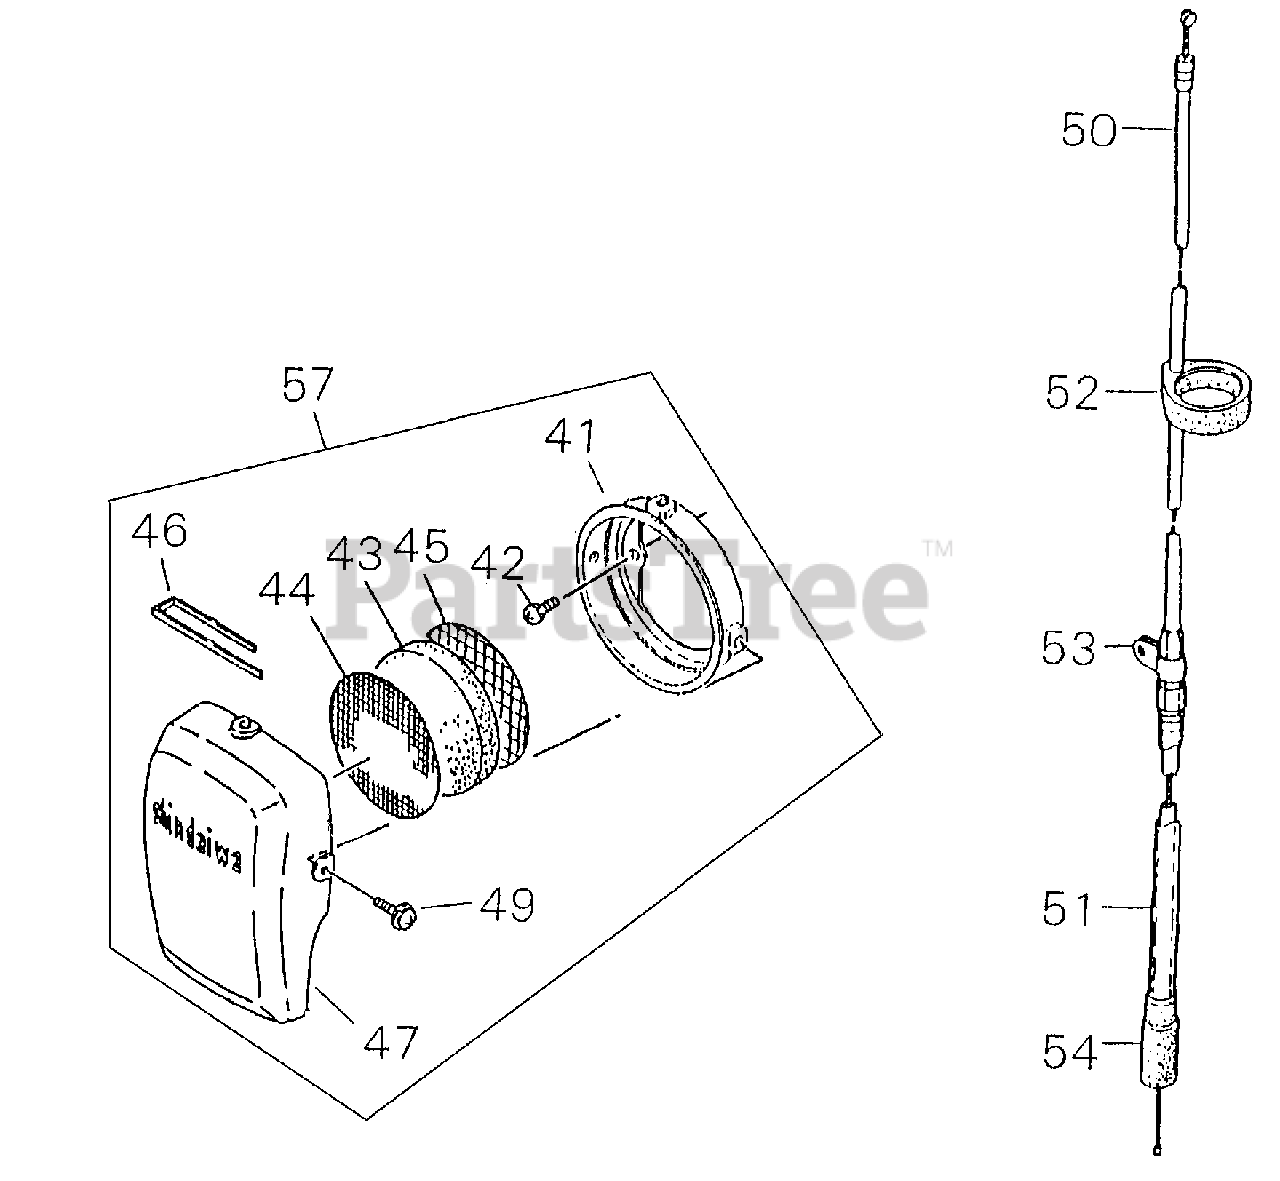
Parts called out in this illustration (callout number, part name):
41	CASE, AIR FILTER
42	SCREW
43	FILTER, AIR - FOAM
44	SCREEN - OUTER
45	SCREEN - INNER
46	CLIP
47	COVER, AIR FILTER
48	LABEL - CHOKE
49	SCREW
50	CABLE
51	PIPE
52	HOLDER, CABLE
53	CLAMP, CABLE
54	CAP, DUST
57	AIR CLEANER ASSY
